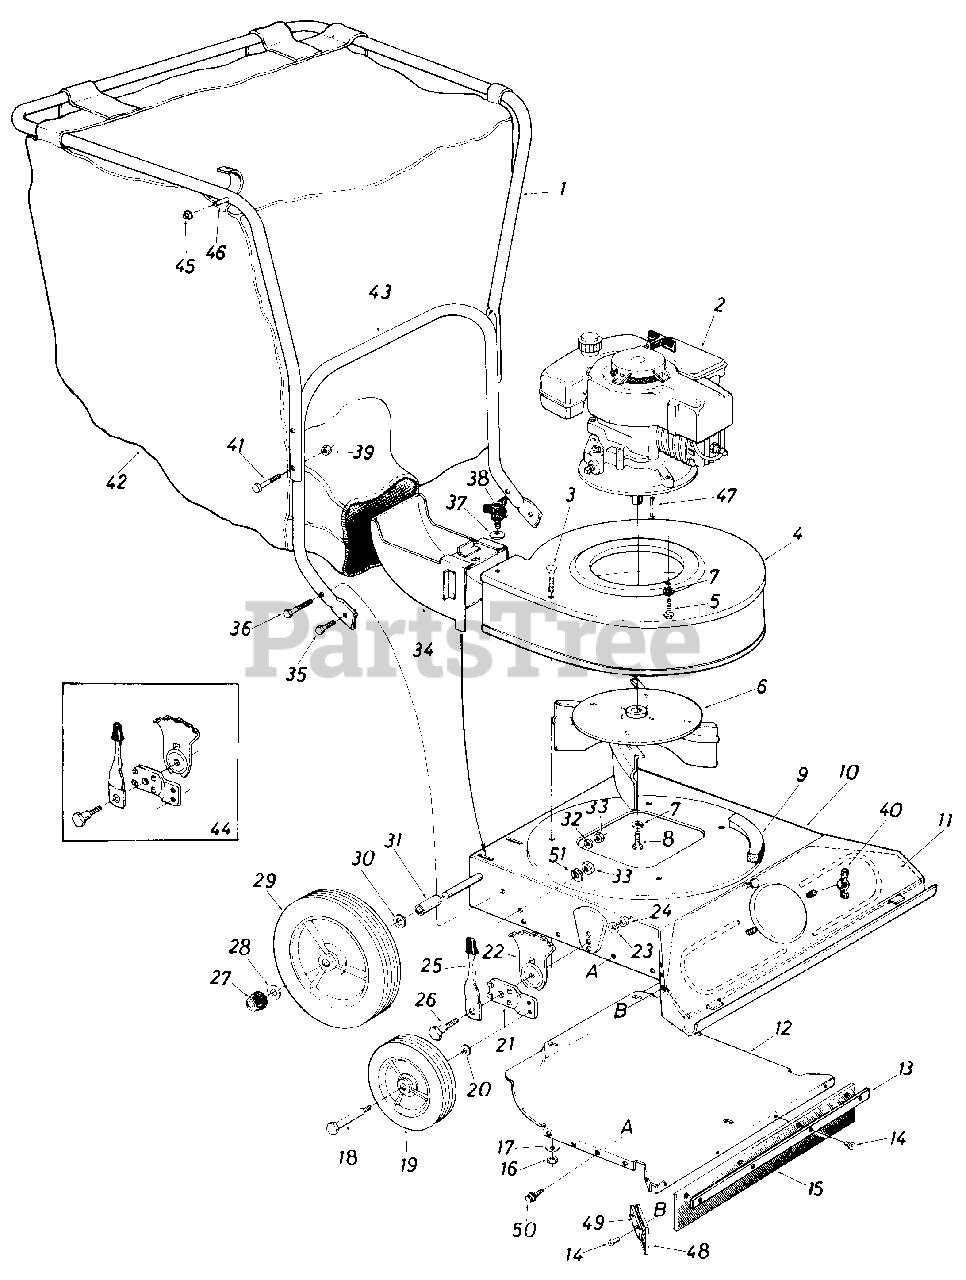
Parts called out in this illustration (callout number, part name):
1	Upper Handle (Painted)
2	Engine
3	Carriage Bolt 5/16-18 x .62" Lg.
4	Blower Housing Ass'y.
5	Hex Tap Scr. 3/8-16 x 1.00" Lg.
6	Impeller Ass'y.
7	L. Wash. 3/8" I.D*
8	Hex Bolt 3/8-24 x 1.0" Lg. w/Patch
9	P.V.C. Foam Strip (4 Pcs. 12" Lg.)
10	Vacuum Deck Ass'y.
11	Front Baffle Ass'y.
12	Lower Baffle Ass'y.
13	Wiper Retaining Strip
14	Pop Rivet .188" Dia.
15	Nozzle Wiper Rear
16	Hex Nut 5/16-18 Thd.
17	Bell.-Wash. .34" I.D. x .87" O.D.
18	Shld. Bolt 1/2" Dia. x 1.45" Lg. (3/8-16)
19	Wheel Ass'y. Comp. 8 x 1.75" - Front
20	Bell.-Wash. .33" I.D. x 1.12" 0. D.
21	Wheel Pivot Bar
22	Index Plate
23	Bell.-Wash. .39" I.D. x 1.12" 0. D.
24	Hex Nut 3/8-16 Thd.
25	Spring Lever Ass'y. w/ Knob
26	Shoulder Bolt .500" x 7/16" Lg. (3/8-16)
27	Push Cap .50" Rod (Black)
28	Fl. Wash. 1/2" I.D. x 1.0" O.D. x .06
29	Wheel Ass'y. Comp. 10 x 1.75" Rear
30	Fl. Wash. 1/2" I.D. x 1.0" O.D. x .06
31	Wheel Spacer 1/2" I.D. x 15/16"
32	Bel Wash. .39" Ln. x 1.12" O . D.
33	Hex Nut 3/8-16 Thd.
34	Air Duct Ass'y.
35	Hex Bolt 3/8-16 x .75" Lg.
36	Hex Bolt 3/8-16 x 1.50" Lg.
37	Bell.-Wash. .34" I.D. x .87" O.D.
38	Thumb Scr. 5/16-18 x .75" Lg.
39	Hex Cent. L. Nut 1/4 20 Thd.
40	Wing Nut 1/4 20 (Plastic)
41	Hex Bolt 1/4-20 x 1.75" Lg.
42	Vacuum Bag (6.6 Bushel)
43	Lower Handle (Painted)
44	Height Adjuster Ass'y. Comp. R.H.
45	Push Speed Nut .25" Dia.
46	Stud Pin .250" Dia. x 1.75" Lg.
47	Sq. Key 3/16 x 3/16 x l.OO"Lg.
48	Nozzle Wiper Side
49	Wiper Retaining Strip
50	Hex Wash. Hd. "F" Tap Scr. #l O
51	L-Wash. 3/8" I.D.
